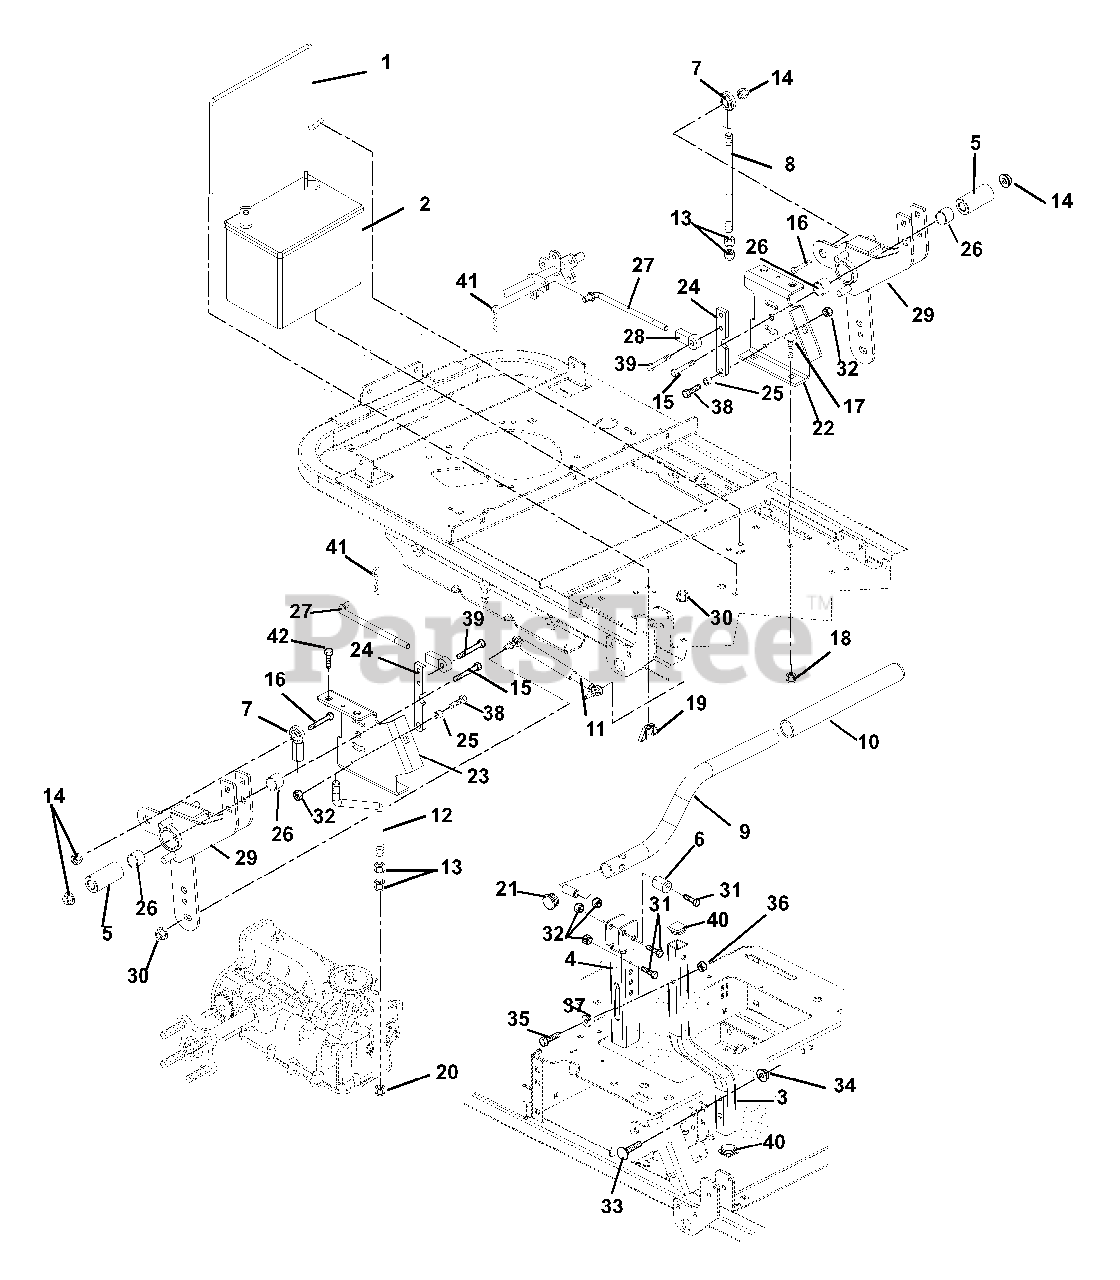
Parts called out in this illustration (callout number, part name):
1	BATTERY ROD
2	BATTERY, 300 CCA 10U1L
2	BATTERY W/ TUBE
3	CONTROL ARM
4	CHANNEL, HANDLEBAR ADJUSTMENT
5	BSHG, SPCR .502X.997X2.03 PM
6	BSHG,ECCEN .328X.750X1.01 PM
7	ROD END, 1/2 RH
8	ROD-TRANSAXLE LH
9	HANDLEBAR
10	GRIP - HANDLEBAR
12	ROD-TRANSAXLE RH
13	NUT-JAM .50-20 GR2 YWZC
14	@NUT-LK-TOP-FLG .50-13 YWZC
15	@BLT-HEX .50-13X3.00 GR5 YWZC
16	@BLT-HEX .50-13X1.75 GR5 YWZC
17	@BLT-RDHDSQNK .38-16X1.00 G5YZ
18	@NUT-LK-NYL-FLG .38-16 YWZC
19	NUT-LK WING .250-20 YWZC
20	NUT-LK-JAM-NYL .50-20 GR2 YWZC
21	CAPLUG, HANDLEBAR
22	WMT, CONTROL LH
23	WMT, CONTROL RH
24	BRACKET, NEUTRAL STOP
25	BSHG, SPCR .330X.500X.385
26	BRG, 1.00 X 1.12 X .75
27	LINK, BRAKE ROD
28	ROD END, .38 RH
29	WMT, STEERING CONTROL
30	NUT, TOP LOCK FLG 8X1.25 YWZC
31	@BLT-HEX .31-18X1.75 GR5 YWZC
32	@NUT-LK-NYL-FLG .31-18 YWZC
33	@BLT-RDHDSQNK .31-18X1.75 G5YZ
34	@NUT-LK-TOP-FLG .31-18 YWZC
35	@BLT-HEX .25-20X1.75 GR5 YWZC
36	@NUT-LK-NYL .250-20 YWZC
37	BSHG-FLG .265X.437X.250X.750
38	@BLT-HEX .31-18X1.25 GR5 YWZC
39	@BLT-HEX .38-16X.75 GR5 YWZC
40	CAPLUG SQR 1-14-20
41	PIN-HAIR INT .08X.18X1.18 YWZC
42	SCR-CAP .38-16X2 HSHD PRECT 30
